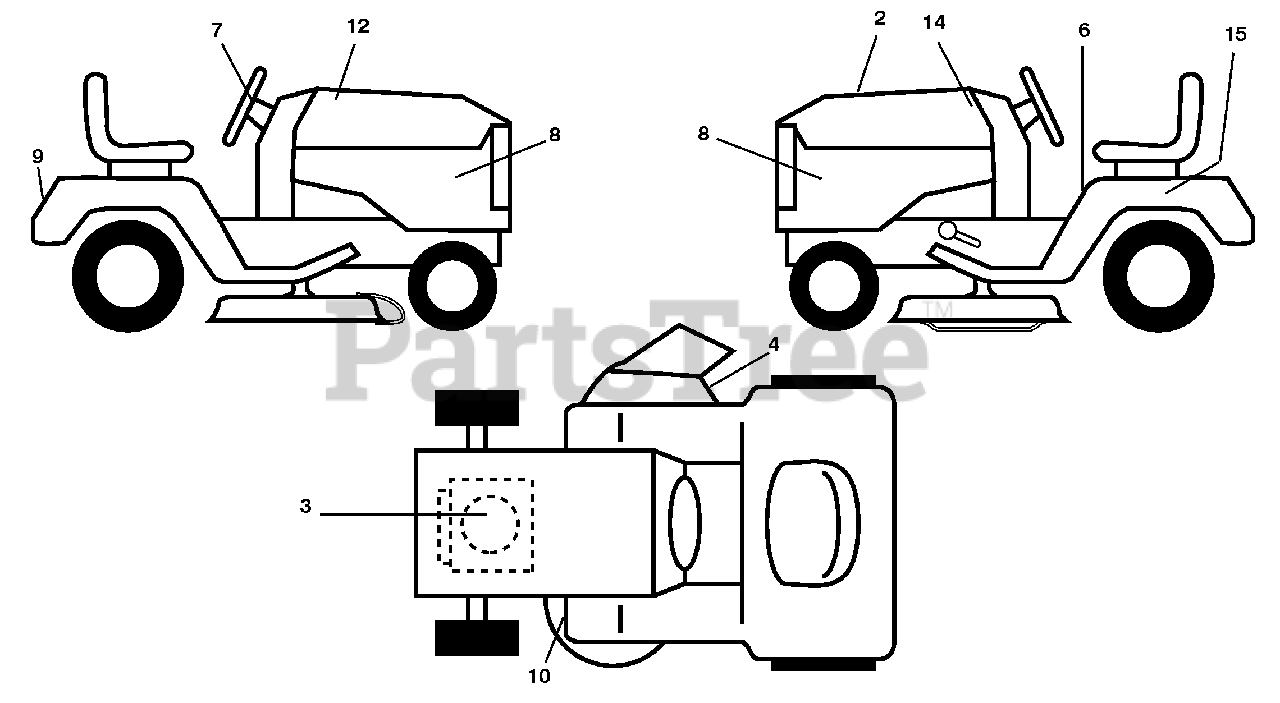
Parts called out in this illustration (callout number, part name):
2	Decal, Replacement
3	Decal, Engine HP
4	Decal, Warning
6	Decal, Fender Warning (E&F)
7	Decal, Ins Str Wh
8	Decal, Side Panel
9	Decal, Fender
10	Decal, V-Belt Sch.
12	Decal, Hood RH
14	Decal, Hood LH
15	Decal, Caution, Battery
15	Decal, Warning Spark Arrestor
15	Decal, Handle Lft Height Adj.
15	Manual, Operator's, English & French
15	Manual, Parts, English & French
